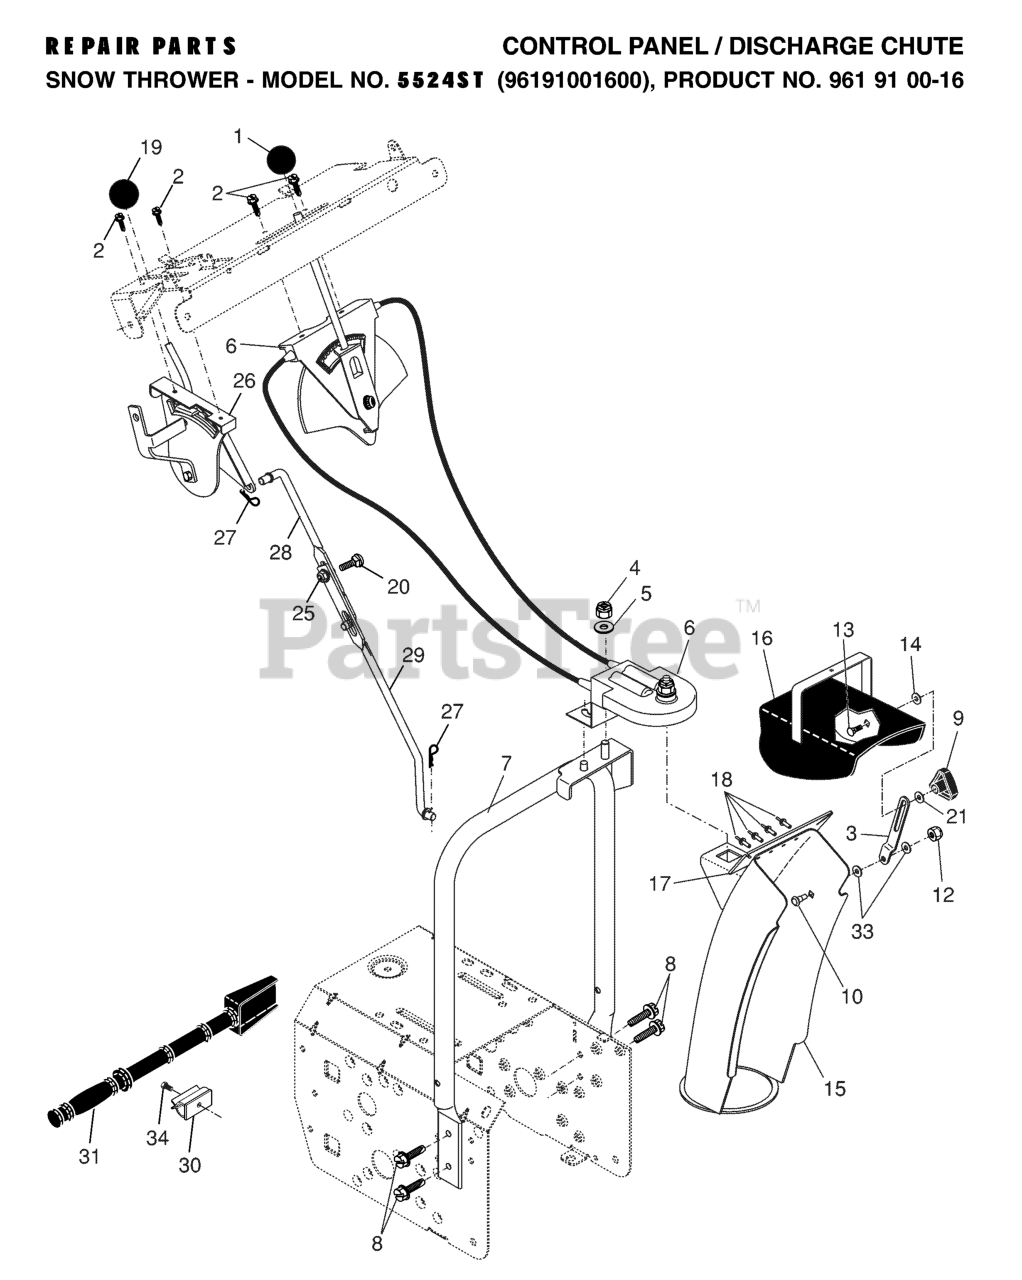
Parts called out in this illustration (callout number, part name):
1	RED KNOB SHIFTER
2	SCREW #10-24 X 5/8
3	STRAP, CHUTE
4	NUT
5	WASHER
6	CONTROL ASSY, CHUTE ROTATER
7	SUPPORT, PIVOT
8	SELF-TAPPING SCREW 5/16-18X3/4
9	KNOB, DEFLECTOR
10	SHOULDER BOLT
12	NUT.HEX.FLANGE.1/4
13	BOLT
14	WASHER, NYLON FRICTION
15	CHUTE ASSEMBLY
16	DEFLECTOR.WELDMENT.PNT.ORANGE
17	SEAL, DEFLECTOR
18	RIVET BLIND
19	KNOB LEVER, BLACK
20	BOLT
21	WASHER.20X8.5
25	NUT.FLANGE.5/16
26	HEAD ASSY SPEED
27	SPRING RETAINER
28	ROD, UPPER SPEED CONTROL
29	ROD, LOWER SPEED CONTROL.SNOW
30	CLIP.CLEANOUT.TOOL
31	CLEAN OUT TOOL
33	WASHER, NYLON FRICTION
34	SCREW.HWH.13-16-5.8.BZP
